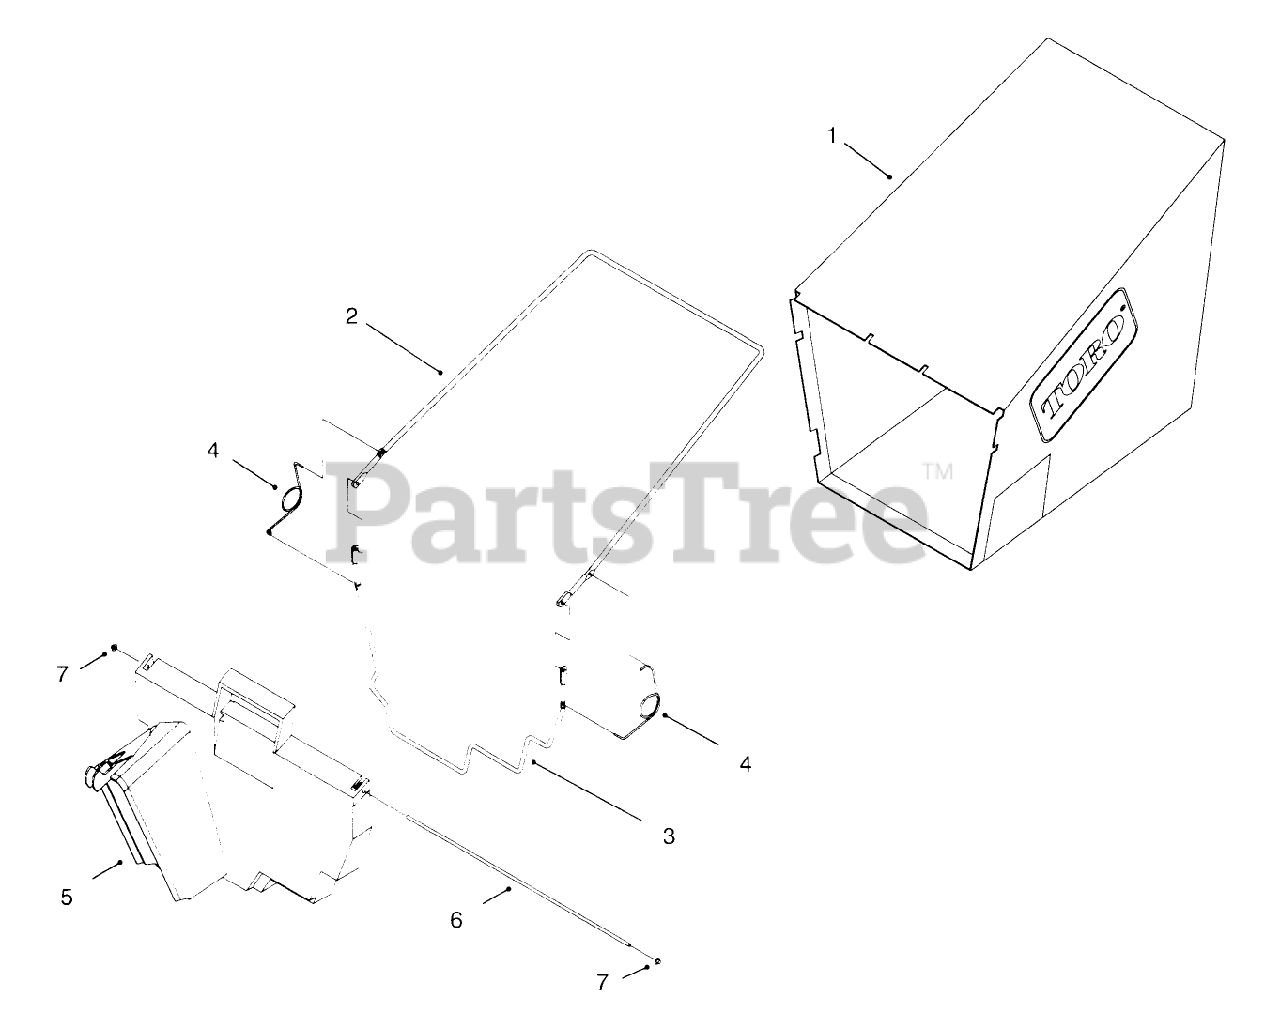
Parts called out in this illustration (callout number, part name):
1	BAG-GRASS
2	FRAME-BAG, UPPER
3	FRAME-BAG, LOWER
4	SPRING
5	DOOR-BAG
6	HINGE-DOOR, BAG
7	NUT-PUSH
